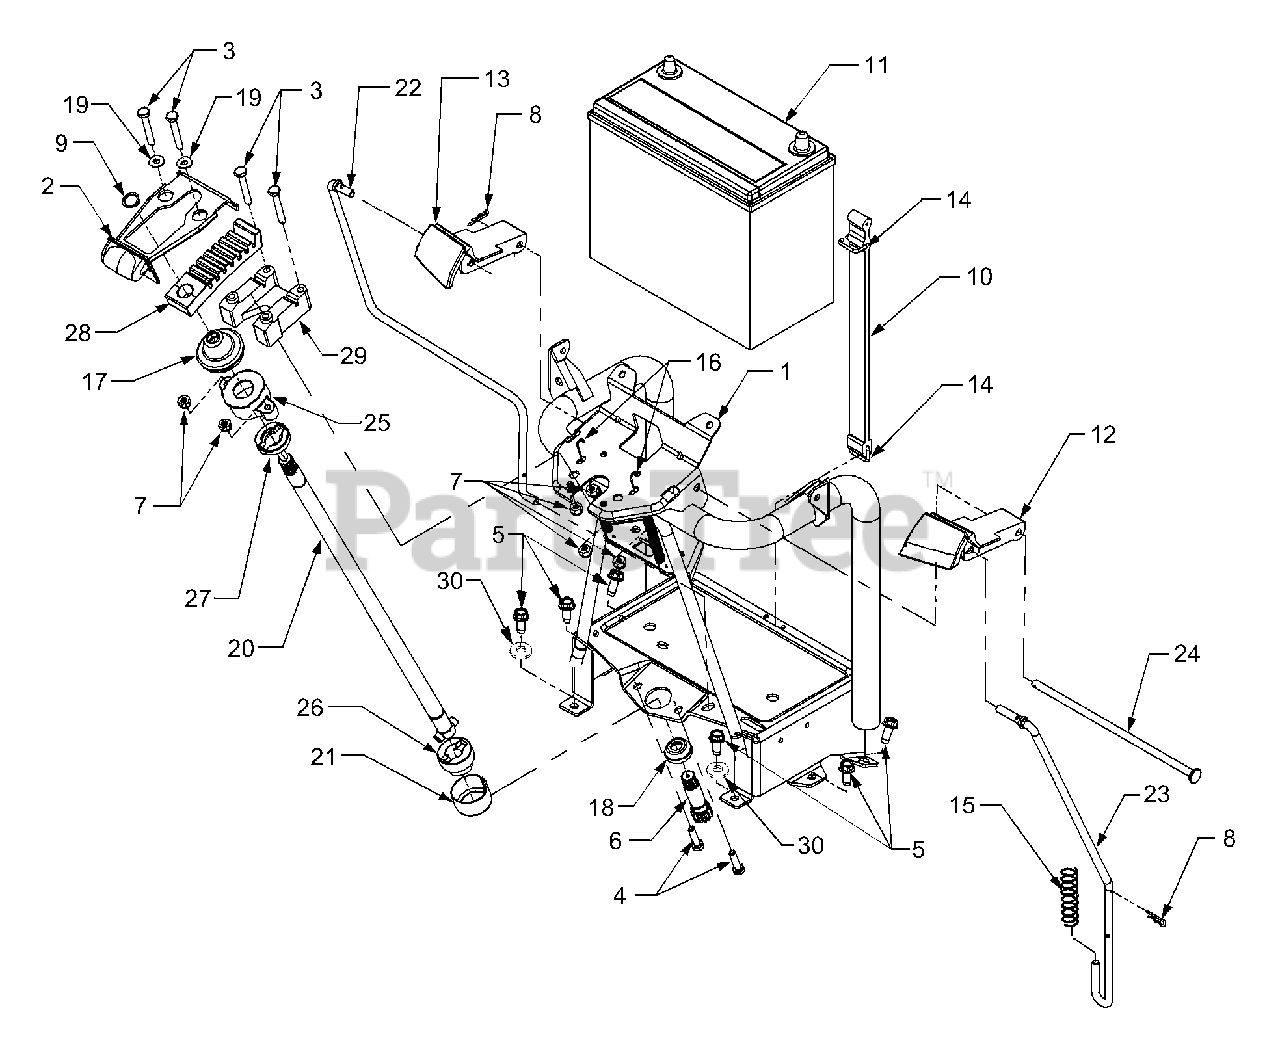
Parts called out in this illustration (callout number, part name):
1	Pedestal Assembly
2	Handle, Tilt
3	Screw, Hex Cap 1/4-20 x 1.75 GR5
4	Screw, Hex Cap 1/4-20 x 1.0 GR5
5	Screw, Hex Wash. Hd. Tapp 5/16-18 x .75
6	Shaft, Lower Steering
7	Nut, Hex Insert Lock, 1/4-20
8	Pin, Internal Cotter
9	Ring, Retaining, .56 Dia Shaft
10	Strap, Battery
11	Battery
12	Lever, Park Brake
13	Lever, Cruise
14	Hook, Wire Rectangular
15	Spring, Compression, .676 x 2.57
16	Spring, Extension
17	Boot, Tilt Wheel Coupling
18	Boot, Shaft Cover
19	Washer, Flat, .271 x .63 x .065
20	Shaft, Upper Steering
21	Bearing, Sleeve, 1.44 x 1.5 x .812
22	Rod, Cruise Control
23	Rod, Parking Brake
24	Rod, Cruise/Brake Pivot
25	Housing, Tilt Wheel Coupling
26	Coupling Half, Bottom
27	Coupling Half, Top
28	Index, Tilt Steering
29	Block, Tilt Steering
30	Washer, Flat, .344 x .688 x .065
